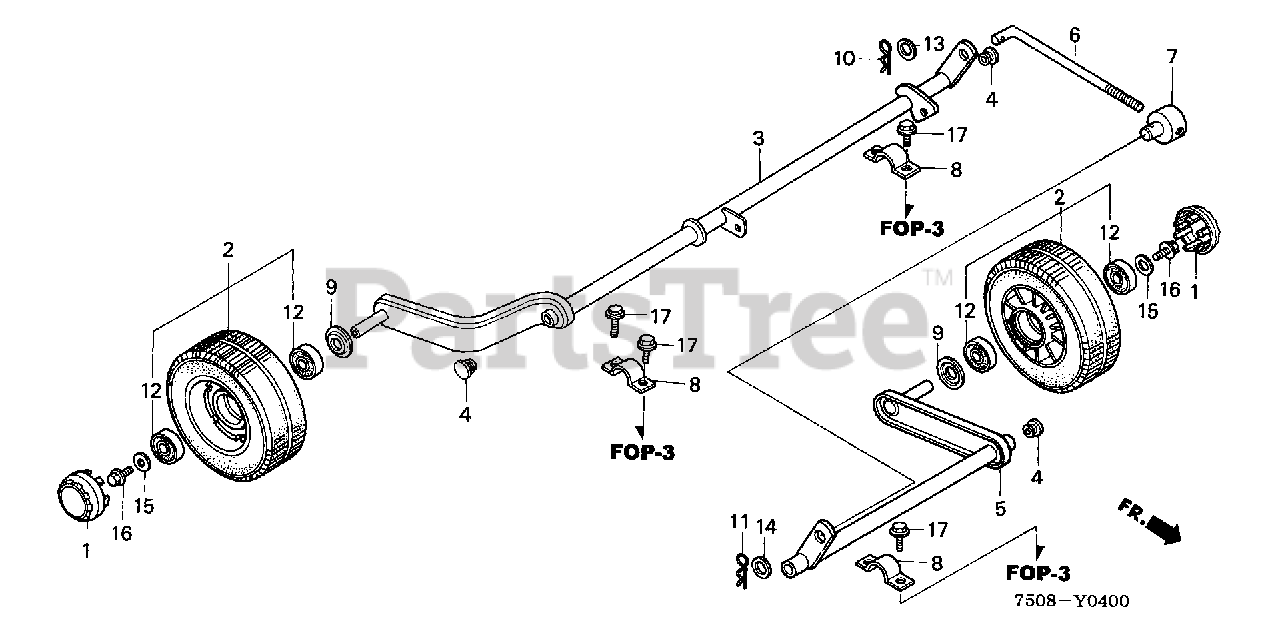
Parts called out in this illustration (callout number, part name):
1	CAP, WHEEL
2	WHEEL (6-2.0)
4	CAP, WHEEL SHAFT
5	SHAFT, L. WHEEL
6	BAR, ADJUSTING
7	PIN, ADJUSTING
8	BRACKET, R. SHAFT
9	WASHER, SPECIAL (12MM)
10	PIN, LOCK (2.3MM)
11	PIN, LOCK (2.3MM)
12	BEARING, RADIAL BALL
13	WASHER, FLAT (12MM)
14	WASHER, PLAIN (14MM)
15	WASHER, PLAIN (6MM)
16	BOLT, FLANGE (6X12)
17	BOLT, FLANGE (8X14)
